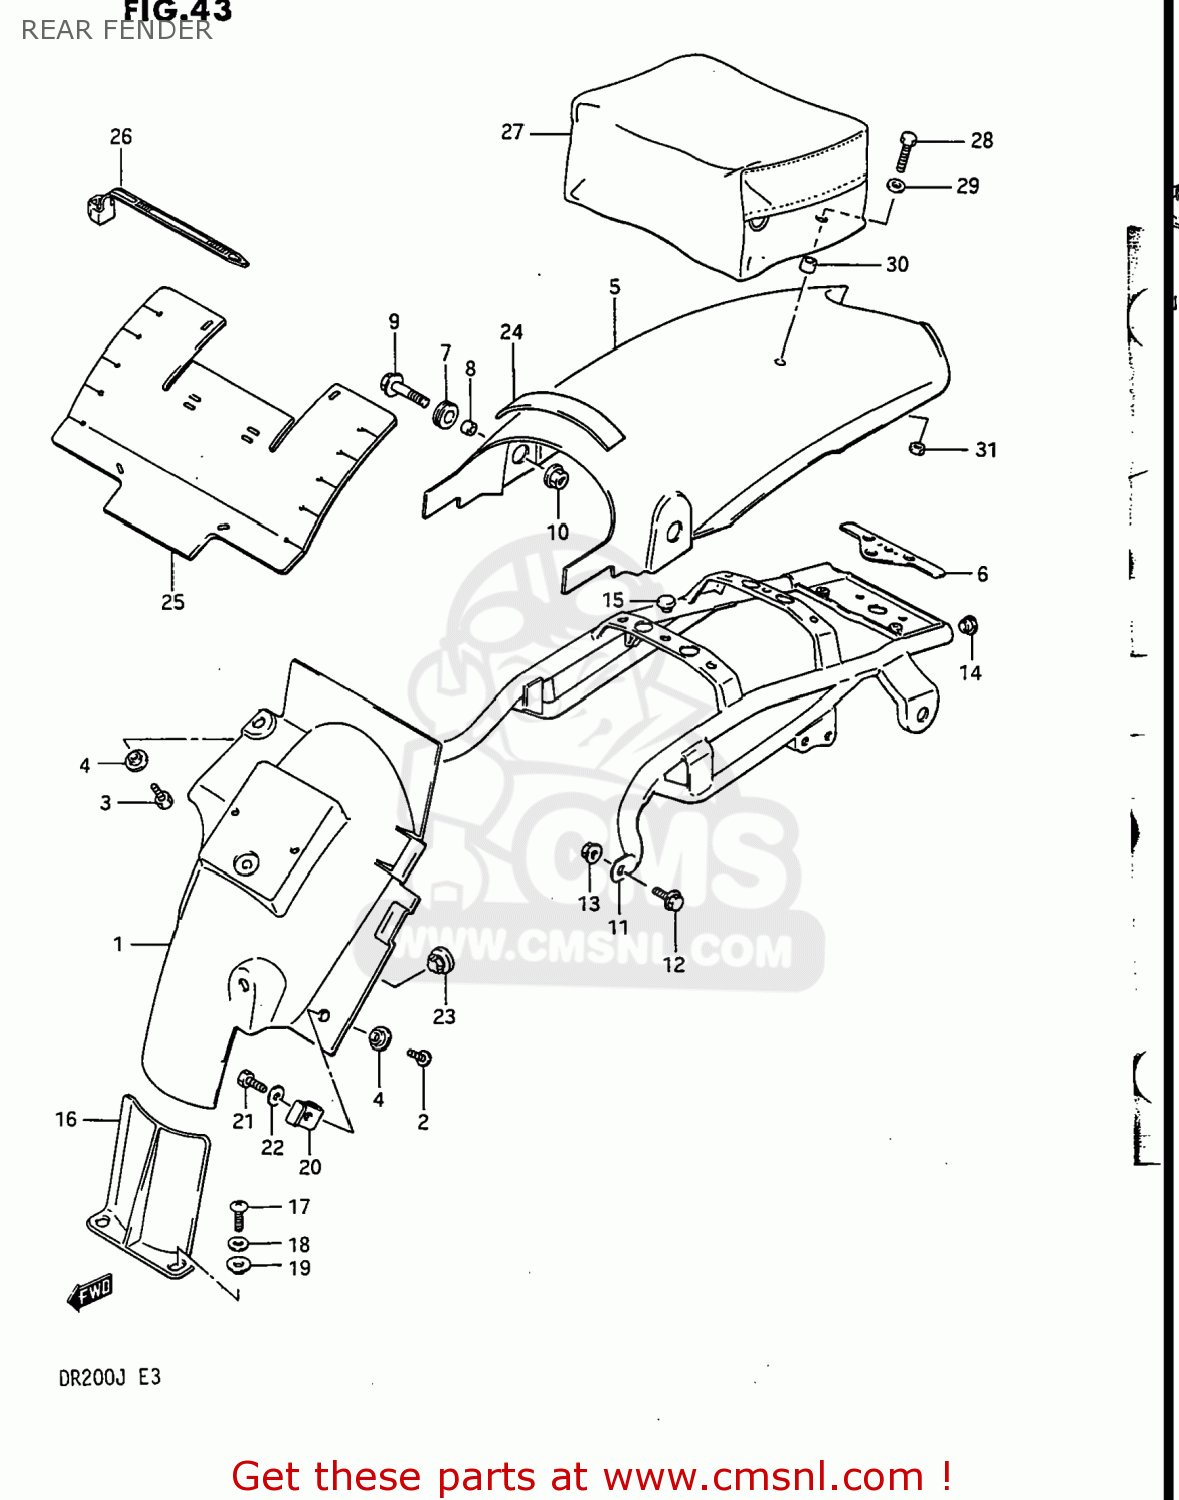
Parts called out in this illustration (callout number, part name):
1	BODY,RR FENDER FR
2	SCREW 6X12
3	BOLT 6X16
4	WASHER
5	FENDER,REAR
6	CUSHION,RR FENDER
7	CUSHION
8	SPACER (8.2X12X7.5)
9	BOLT
10	NUT
11	REINFORCEMENT,REAR FENDER
12	BOLT
13	NUT
14	PLUG
15	CUSHION
16	GUARD,RR UNIT MUD
17	SCREW
18	WASHER(6.5X16X1.2)
19	WASHER,LOCK
20	BRACKET,FENDER LOWER,LEFT
21	BOLT
22	WASHER (6.5X20X1.2)
23	CAP(OD:16)
24	CUSHION(25X185X15)
25	FLAP,AIR CLEANER MUD
26	CLAMP(L:125)
27	BAG ASSEMBLY,SEAT TAIL
28	BOLT
29	WASHER
30	SPACER (6.1X9X9)
31	NUT
